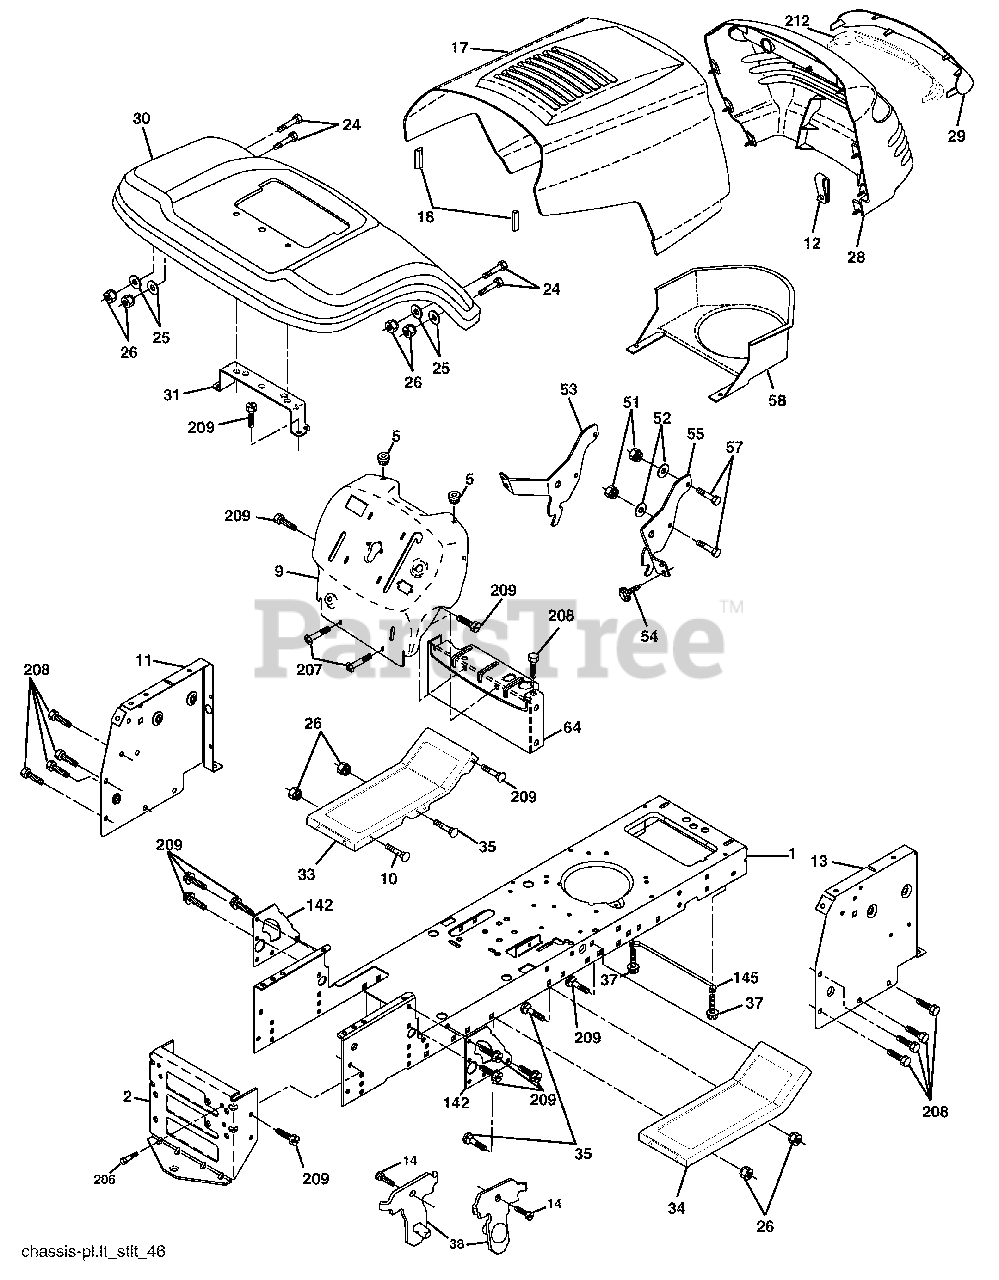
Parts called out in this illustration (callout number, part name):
1	Chassis
2	Drawbar
3	Screw 3/8-16 x .75
5	Bumper Hood/Dash
10	Bolt Carriage 3/8-16 x 1
11	Panel Dash Lh
12	Clip Tinnerman
13	Panel Dash Rh
14	Screw Thdrol 3/8-16 x 1-1/4
17	Hood LT/PL
18	Bumper Hood
24	Bolt Fin Hex 3/8-16 x 1 Gr 5
25	Washer 13/32 X 13/16 X 12 Ga
26	Nut Lock Hex W/Ins 3/8-16 Unc
28	Grille LT/PL
29	Lens LT/PL
30	Fender Footrest STLT Pnt
31	Bracket Support Fender
33	Footrest Pnt Lh
34	Footrest Pnt Rh
35	Bolt Rdhd Sht Sqnk 3/8-16 x 3/4
37	Screw Thdrol 6/16-18 x 1/2 TYT
38	Bracket Asm. Pivot Mower Rear
51	Nut Lock Hex W/Ins 1/4-20
52	Washer 9/32 x 7/8 x 16 Ga.
53	Bracket Grille Lh
54	Screw Hex Wshd 8-18 x 7/8
55	Bracket Grille Rh
57	Bolt Hex 1/4-20 x 3/4
58	Duct Air
64	Dash Lower STLT
142	Plate Reinforcement STLT
145	Rod Pivot Chassis/Hood
206	Bolt Shoulder 5/16-18
207	Screw Thdrol 5/16-18 x 1/2
208	Screw Thdrol 3/8-16 x 1/2
209	Screw Hex Wsh Thdr. 3/8-16 x 3/4
212	Insert Lens Reflect P/L LT
